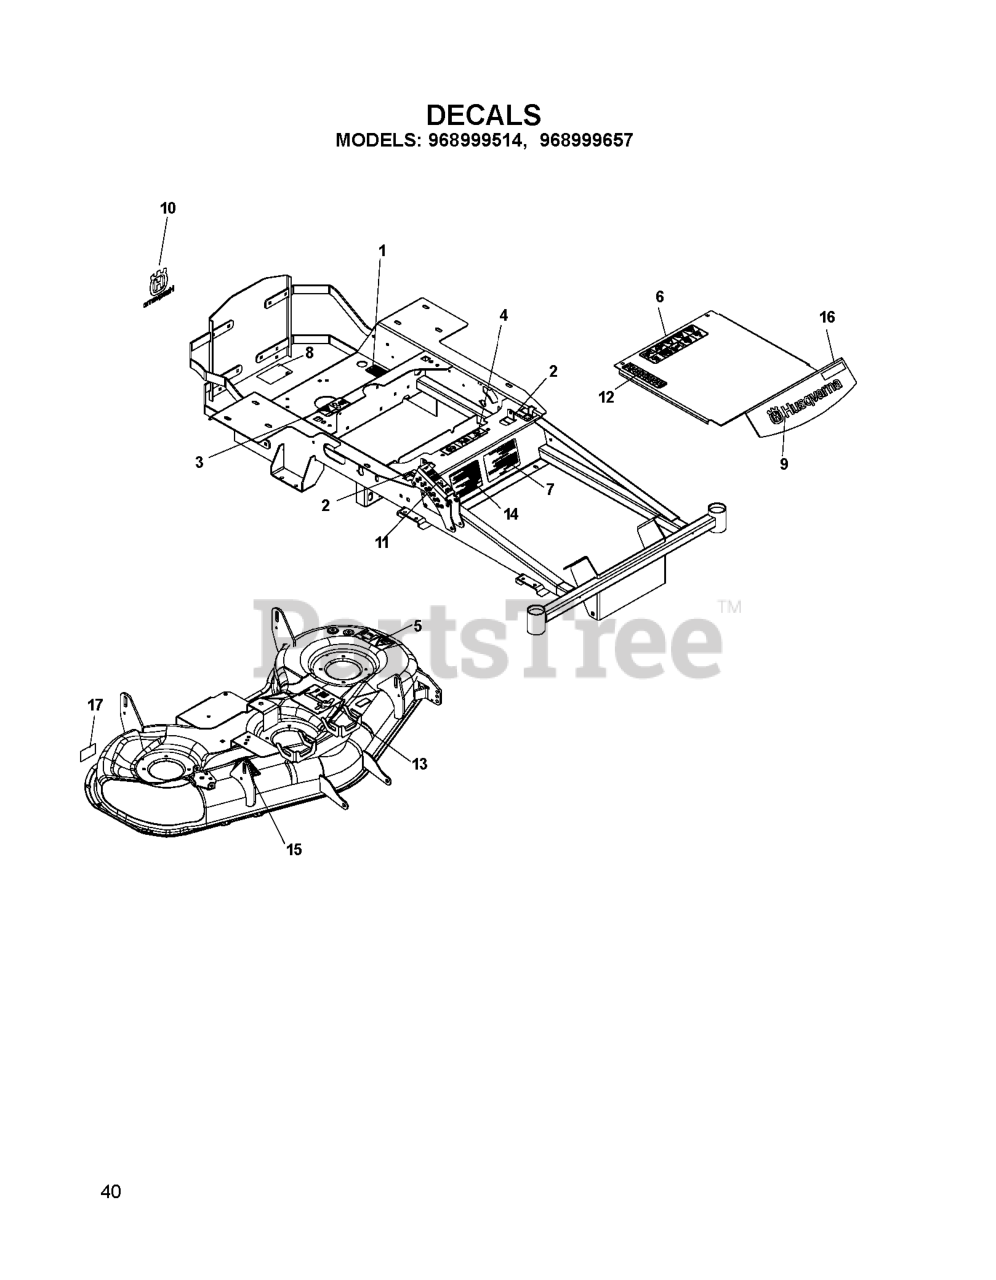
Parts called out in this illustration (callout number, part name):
1	DECAL, PROP. 65
2	DECAL, MOTION CONTROL
3	DECAL, BELT DRIVE
4	EURO DECAL-BATTERY WARNIN6
5	DECAL, EURO SEVERING
6	DECAL, WARNING
7	DECAL, START
8	DECAL, DO NOT TOW
9	DECAL, HUSQ 12" BLUE
10	DECAL, CROWN H 5-1/4 SILVER
11	DECAL, TRANS RELEASE
12	DECAL, HEIGHT ADJUST
13	DECAL, BELT ROUTING
14	DECAL, WARNING
15	DECAL, CPSC
16	DECAL, EZ4624
17	DECAL, CAUTION
